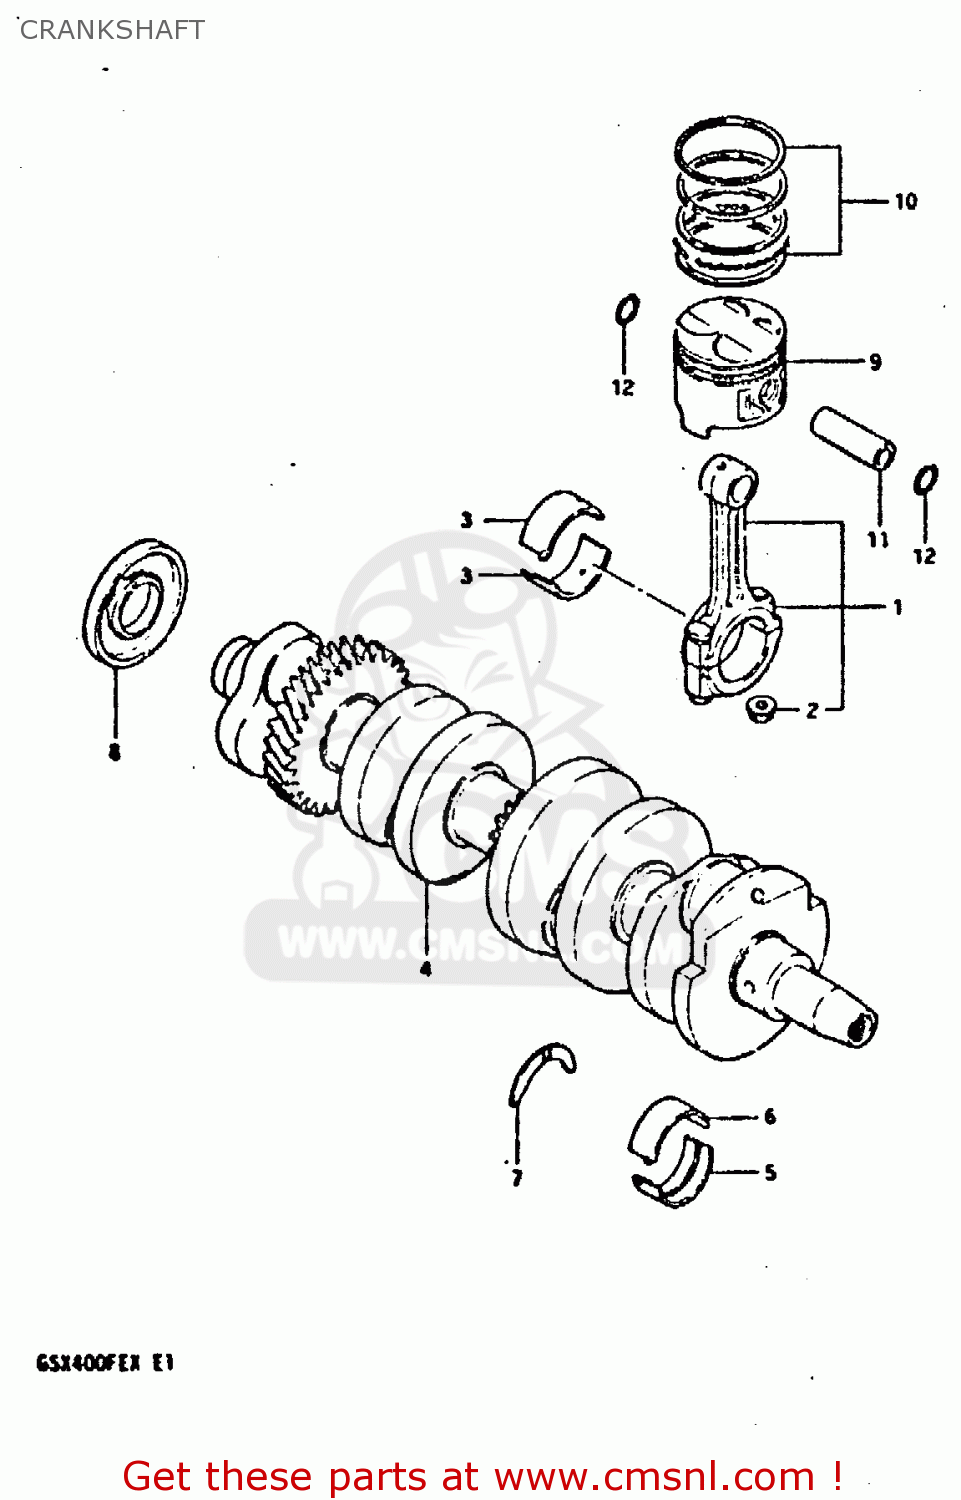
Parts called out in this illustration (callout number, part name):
1	ROD ASSY, CONNECTING
2	NUT
3	BEARING, CRANK PIN
4	CRANKSHAFT
5	BEARING (GREEN)
6	METAL CRANKSHAFT
7	BEARING, CRANKSHAFT THRUST
8	OIL SEAL 30X56
9	PISTON 1.00
10	RING SET
11	PIN,PISTON
12	RING,SNAP 14MM
